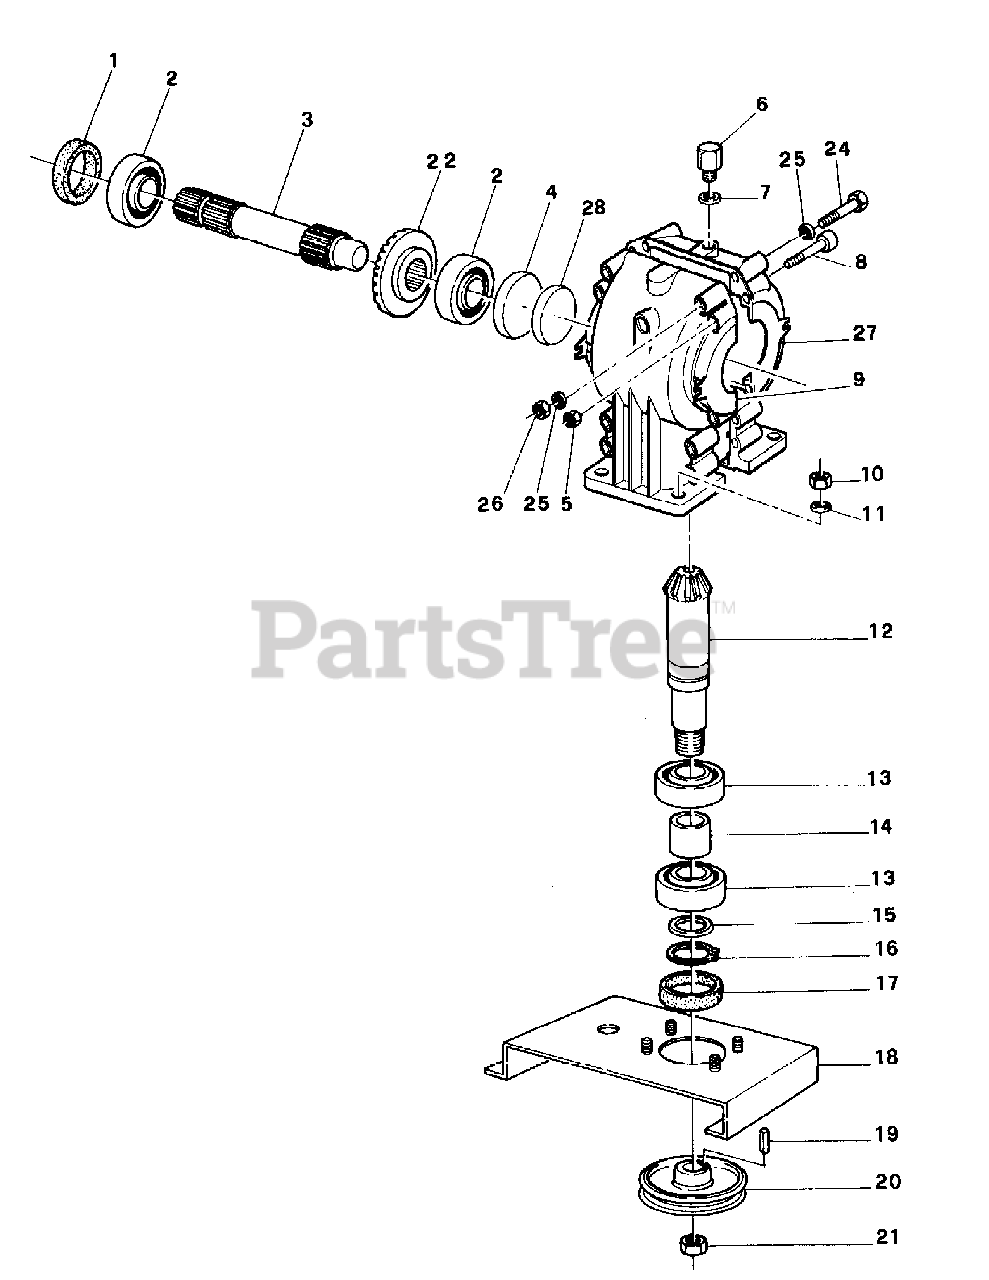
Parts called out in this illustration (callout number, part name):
1	Oil seal 40.68.10
2	Bearing 6208
3	Input shaft
4	Cap
5	Nut M8
6	Breather cap
7	Gasket
8	Bolt TCEI 8x50
9	Gearbox housing without hole
10	Nut M12
11	Spring washer M12
12	Pinion gear
13	Bearing 6207
14	Spacer
15	Spacer washer
16	Outer snap ring M35
17	Oil seal 35.62.10
18	Central plate FM48
18	Central plate FM60
18	Central plate FM72
19	Key 7x8x35
20	Pulley SPB 250x1
21	Nut M25
22	Ring gear
24	Bolt TE 10x120
25	Flat washer M10
26	Nut M10
27	Gearbox housing with hole
